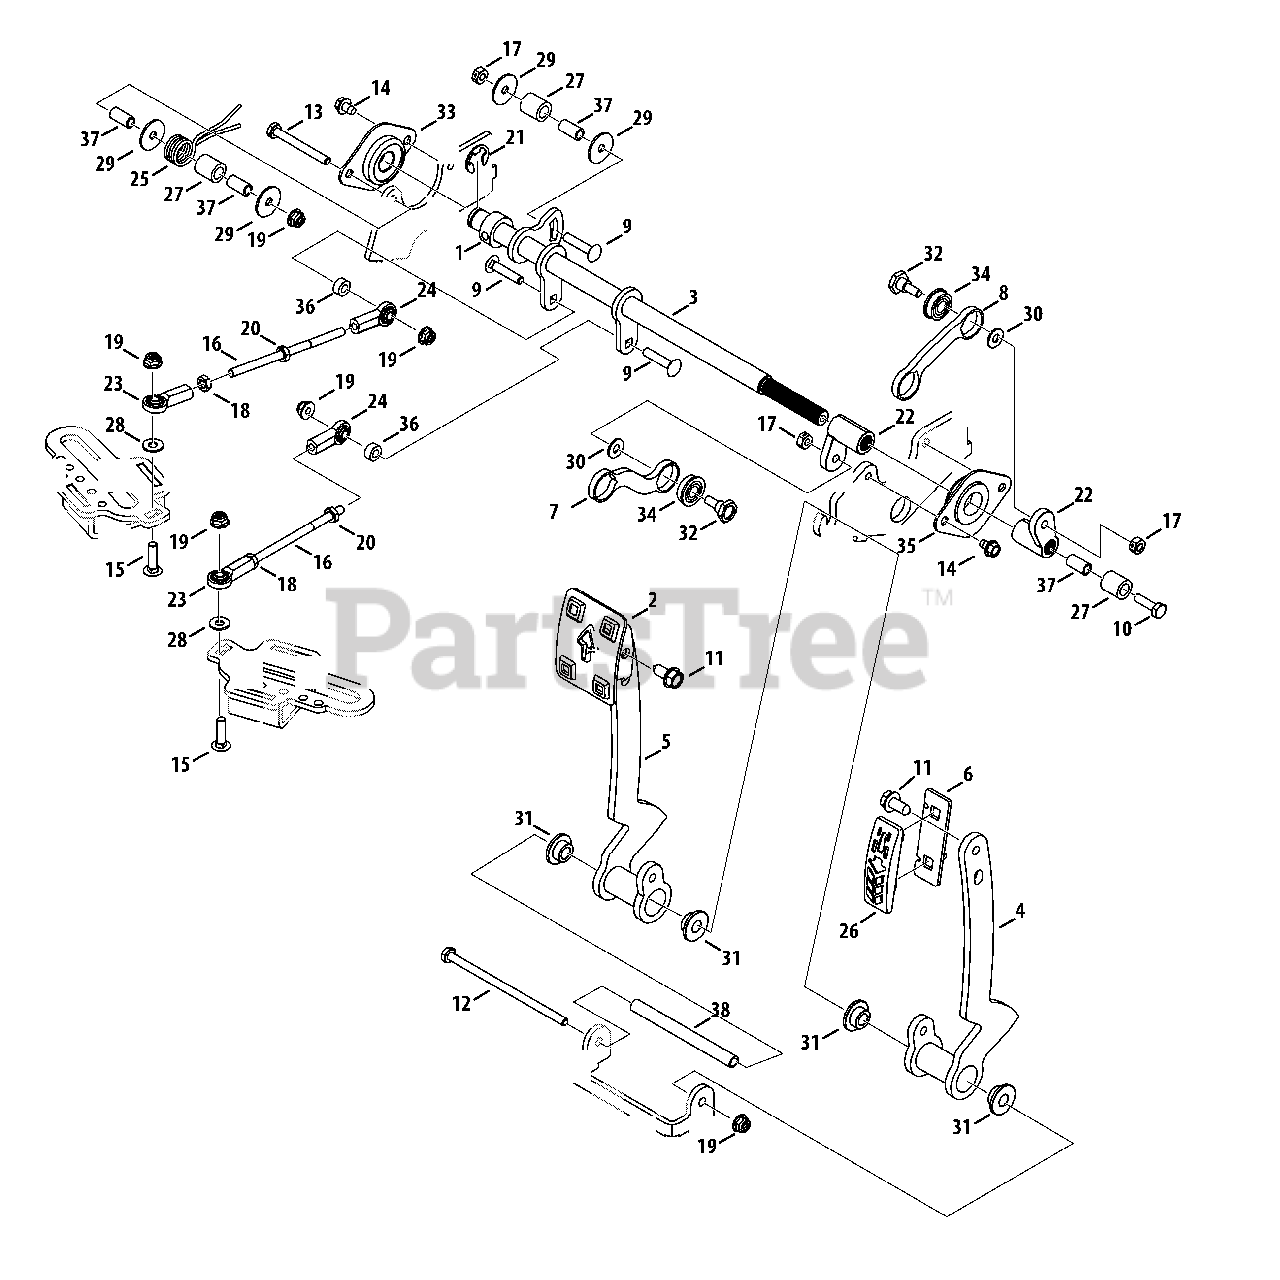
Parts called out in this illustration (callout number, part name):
1	Shaft Collar, .625 x 1.0 x .438
2	Forward Pedal Assembly
3	Speed Control Arm Assembly
4	Reverse Pedal Assembly
5	Forward Pedal Assembly
6	Reverse Pedal Bracket
7	Forward Pedal Link
8	Reverse Pedal Link
9	Carriage Screw, 1/4-20 x 1.25
10	Hex Cap Screw, 1/4-20 x 1.25
11	Screw, 5/16-18 x .750
12	Hex Cap Screw, 1/4-20 x 5.00
13	Hex Cap Screw, 1/4-20 x 2.25
14	Screw, 1/4-20 x .375
15	Carriage Screw, 1/4-20 x 1.00
16	Speed Control Link Rod
17	Nut, 1/4-20, Hexlock
18	Jam Nut, 1/4-28
19	Nut, 1/4-20, Flangelock
20	Jam Nut, 1/4-28, LH
21	E-Ring, .625
22	Pedal Shaft Arm
23	Rod End, 1/4-28
24	Rod End, 1/4-28, LH
25	Torsion Spring, .70 ID
27	Spacer, .385 x .625 x .700
28	Washer, .250 x .630 x .052
29	Washer, .255 x 1.00 x .060
30	Washer, .271 x .630 x .065
31	Shoulder Spacer, .38 x .62 x 1.00
32	Shoulder Screw, .375 x .280, 1/4-20
33	Ball Bearing, .625
34	Bearing, .375 x .875 x .281
35	Ball Bearing, .750
36	Spacer, .256 x .500 x .240
37	Spacer, .260 x .375 x .75
38	Spacer, .255 x .375 x 4.28
